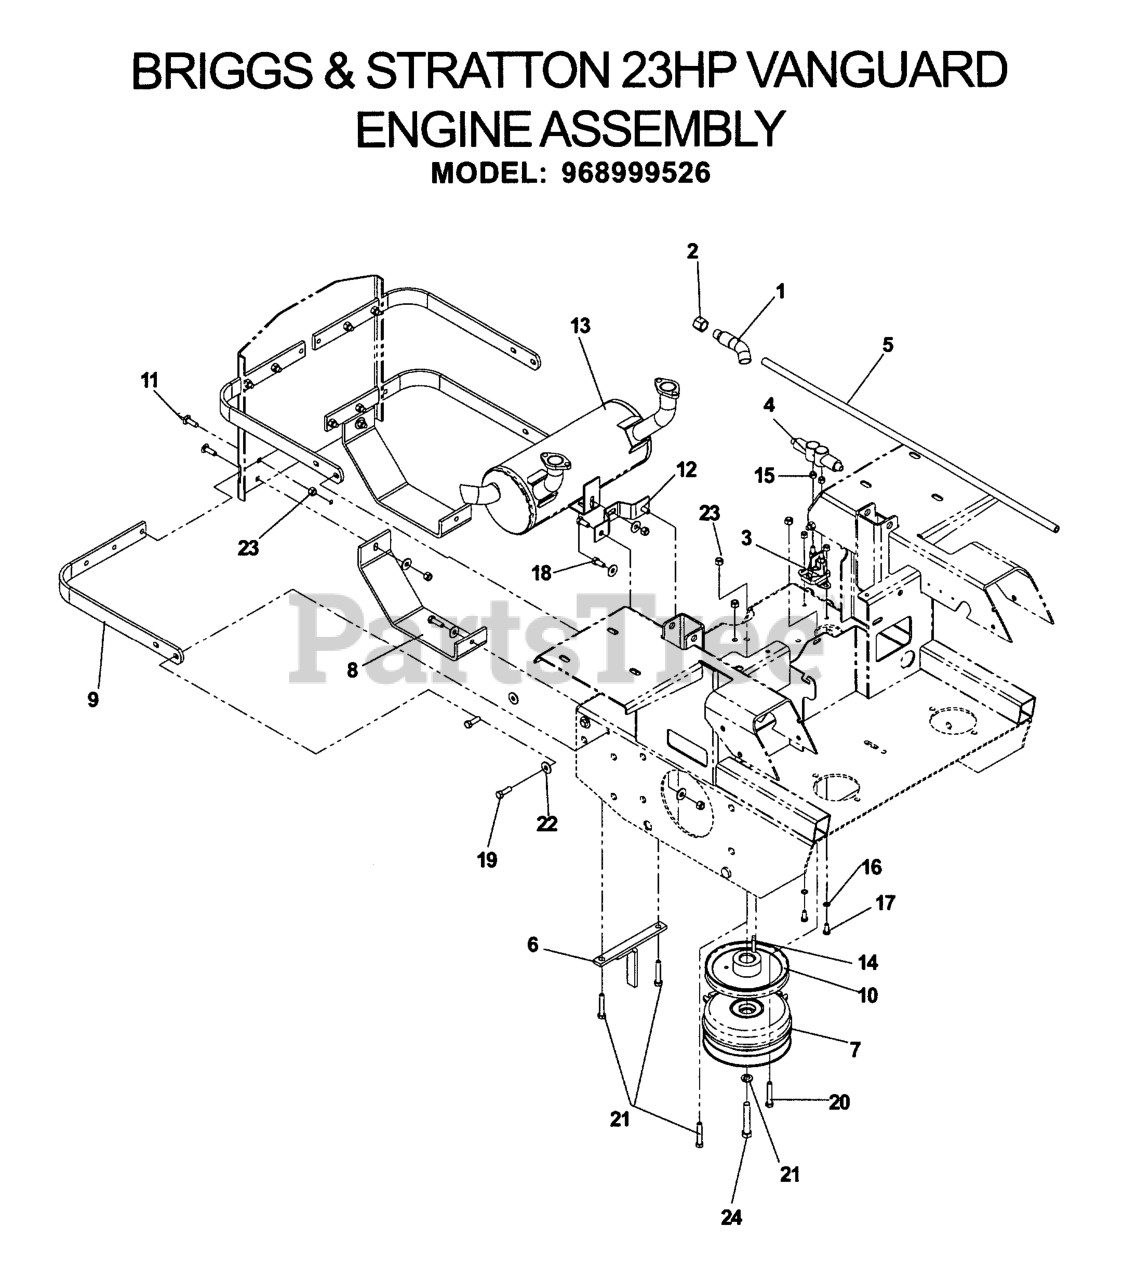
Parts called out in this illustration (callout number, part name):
1	OIL DRAIN HOSE
5	FUEL LINE 29.5"
6	CLUTCH TIE DOWN
7	CLUTCH-200 FT LB(RPLS 5218-102
8	SKID PLATE
9	ENGINE SHROUD BRKT
11	RHSSNB 5/16C X 1.0
12	BRACKET, MUFFLER
13	MUFFLER VANGUARD 23HP
14	KEY, 1/4 SQ X 1 1/4
15	NUT.1/4-20.HEX.NYLOC.ZD
16	WASHER 1/4 INT TOOTH
17	HCS 1/4C X 5/8
18	SCREW 5/16C X 1 HEX CAP
19	HCS 5/16C X 1
20	WASHER 7/16 LOCK
21	HCS 5/16C X 1 3/4
22	WASHER 5/16 FLAT
23	NUT 5/16 NYLOC
24	BOLT 7/16F X 2 1/2
